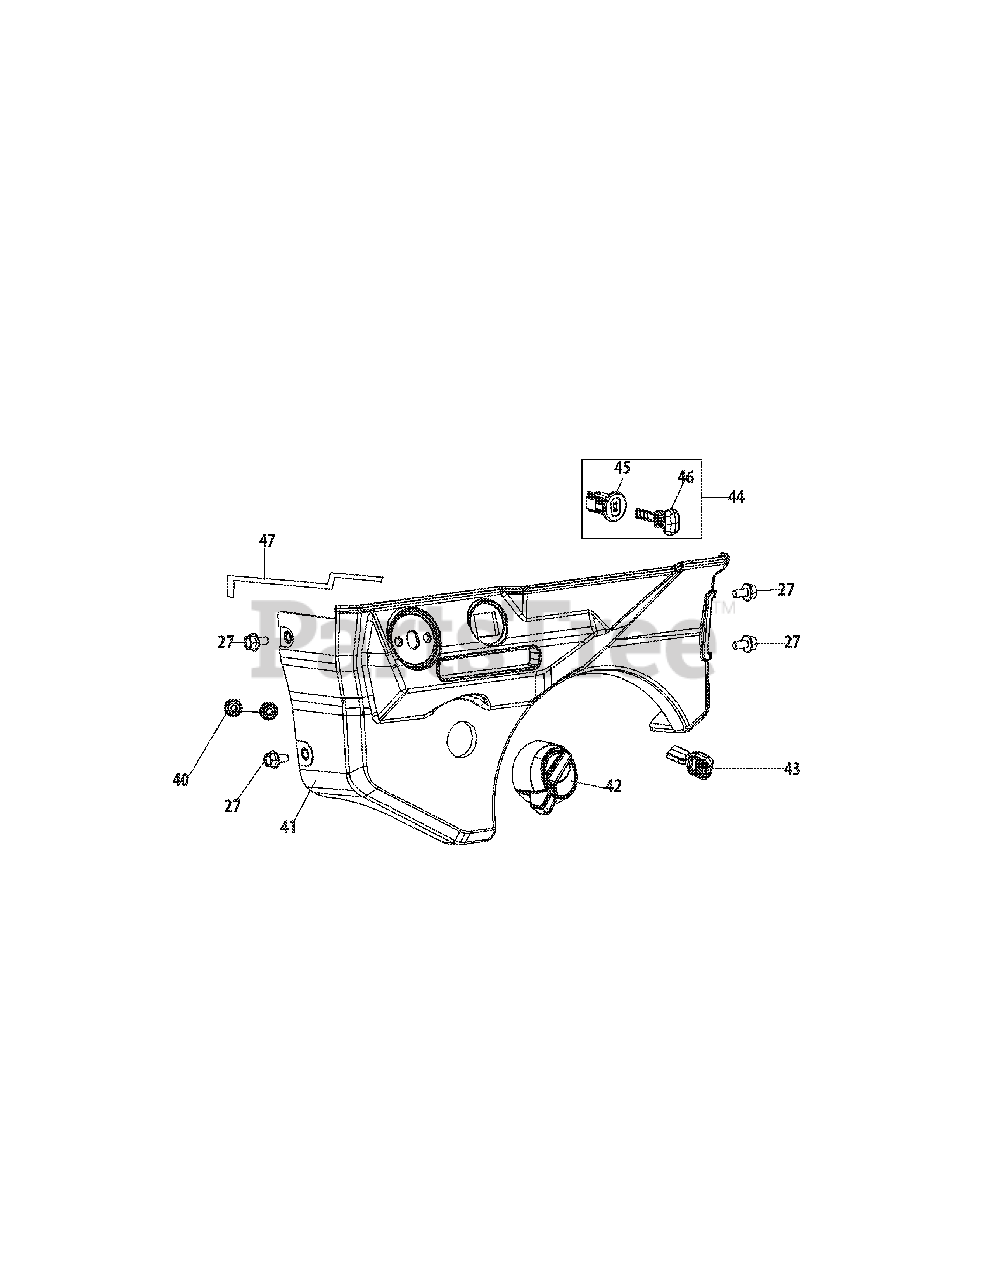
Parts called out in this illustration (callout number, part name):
27	BOLT M6×12
40	FLANGE NUT M6
41	CONTROL PANEL
42	CHOKE LEVER
43	THROTTLE LEVER KNOB
44	ENGINE SWITCH
45	ENGINE SWITCH BASE
46	ENGINE SWITCH KEY
47	CHOKE LINKAGE
